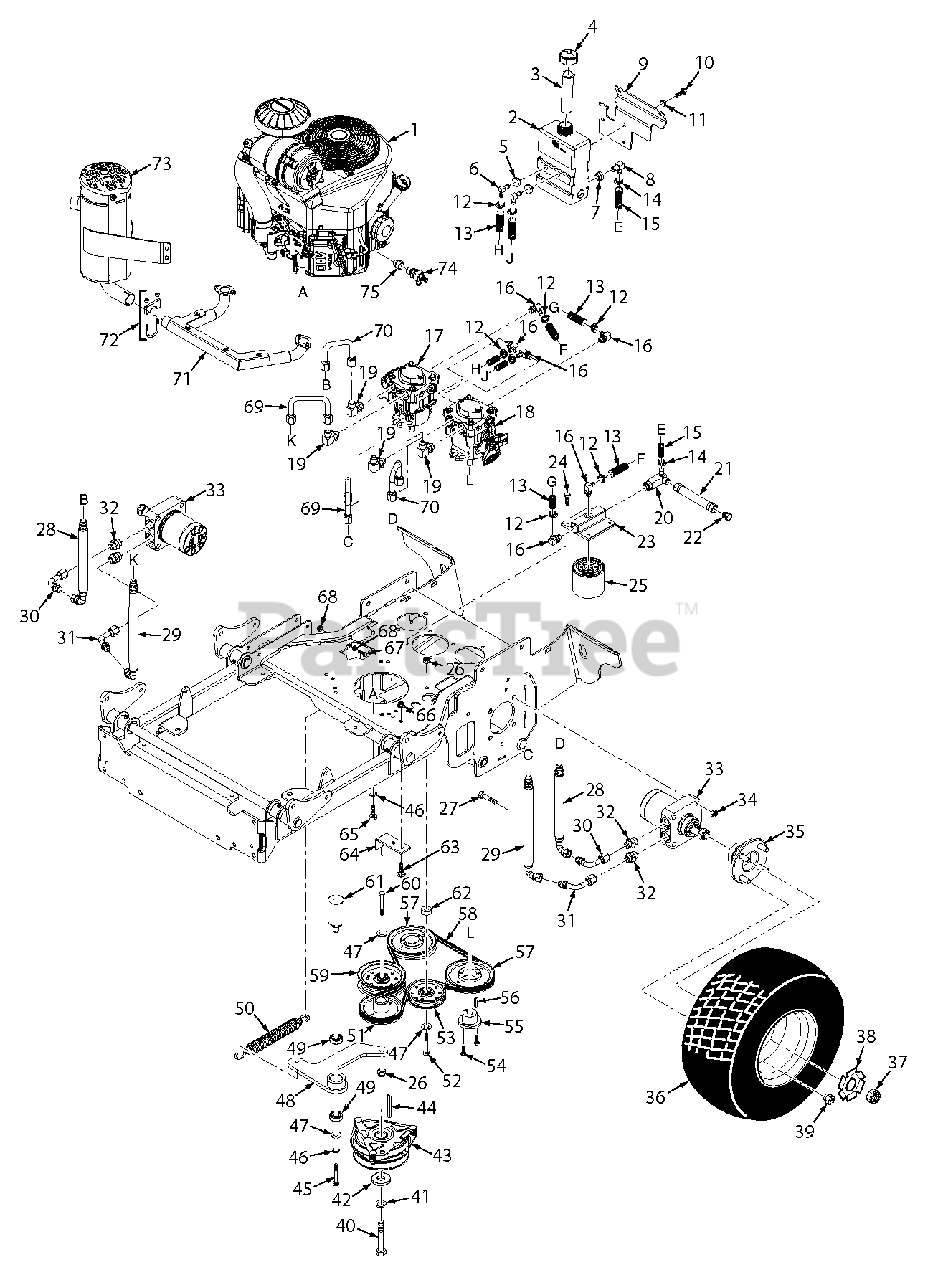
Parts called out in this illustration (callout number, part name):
1	Engine, 15 HP Kawasaki FS
1	Engine, 19 HP Kawasaki FX
2	Hydro Tank Assy., SVRII
3	Insert, Filler Neck
4	Cap, Hydraulic Tank
5	Bushing, .56 Viton
6	Fitting, 90 Degree x .38 Hose
7	Bushing, .78 Viton
8	Fitting, 90 Degree x .50 Hose
9	Bracket, Hydro Tank Mounting
10	Bolt, Hex Head 5/16-18 x 3/4"
11	Lockwasher, 5/16"
12	Clamp, Hose
13	Hose, 3/8" Pucklock (order by inch)
14	Clamp, Hose
15	Hose, 1/2" Pushlock (order by inch)
16	Elbow, 90 Degree O-Ring
17	Pump, SVR
18	Pump, SVR
19	Elbow, 90 Degree
20	Tee, 3/4" O-Ring
21	Drain Hose Assy.
22	Plug, JIC 3/4-16 UNF
23	Filter Head
24	Bolt, Hex Head 5/16-18 x 3/4"
25	Filter
26	Nut, Elastic Stop 3/8-16
27	Bolt, Hex Head 1/2-13 x 2-1/2"
28	Hose Assy., 11-1/4"
29	Hose Assy., 13-1/4"
30	Tube Assy., 1/2 x 2 x 2"
31	Tube Assy., 1/2 x 2 x 3-1/4"
32	Tube, Union 1/2 x 5/8"
33	Wheel Motor
34	Nut, Center Lock 1/2-13
35	Wheel Hub Assembly
35	Wheel Stud
36	Wheel Assy., 20 x 8 - 10
36	Tire, 20 x 8 - 10
36	Rim w/ Valve
37	Hex Castle Nut, 3/4-28
38	Lockwasher, Wheel Motor
39	Wheel Nut
40	Bolt, Hex Head 7/16-20 x 2-1/4" w/ Patch
41	Lockwasher, 7/16"
42	Flatwasher, 7/16-.469 x 1.75 x .25
43	Clutch w/Tag
44	Key, 1/4 x 1/4 x 3-1/2"
45	Bolt, Hex Head 3/8-16 x 3-3/4"
46	Lockwasher, 3/8"
47	Flatwasher, 3/8-.391 x .938 x 105 HD
48	Idler Arm Assy., Pump Drive - SVRII-36
49	Bearing
50	Spring, Transmission Idler
51	Pulley, 4-3/4" OD - 1.125 Bore
52	Bolt, Hex Head 3/8-16 x 2-1/4"
53	Pulley, Idler 4"
54	Bolt, Hex Head 1/4-20 x 1"
55	Tapered Hub, 15mm Bore
56	Key, 5 x 5 x 25mm
57	Pulley, 5.45 OD - Tapered Bore"
58	Belt, Pump Drive - SVRII-36
59	Pulley, Idler 4"
60	Bolt, Hex Head 5/16-18 x 2-1/4"
61	Pivot, Idler
62	Spacer, Idler
63	Bolt, Carriage 5/16-18 x 3/4"
64	Anti-Rotation Weldment
65	Bolt, Hex Head 3/8-16 x 1-1/2"
66	Nut, Serrated Flange 5/16-18
67	Bolt, Hex Head 3/8-16 x 1-1/2"
68	Nut, Serrated Flange 3/8-16
69	Tube Assy., 1/2 x 4" Wide
70	Tube Assy., 1/2 x 3" Wide
71	Exhaust Manifold, 15 HP Kawasaki FS
72	Muffler Clamp
73	Muffler, Kawasaki
74	Oil Drain, SVRII-36
74	Tubing, Oil Drain (order by inch)
75	Fitting, M14 to M20 Male
